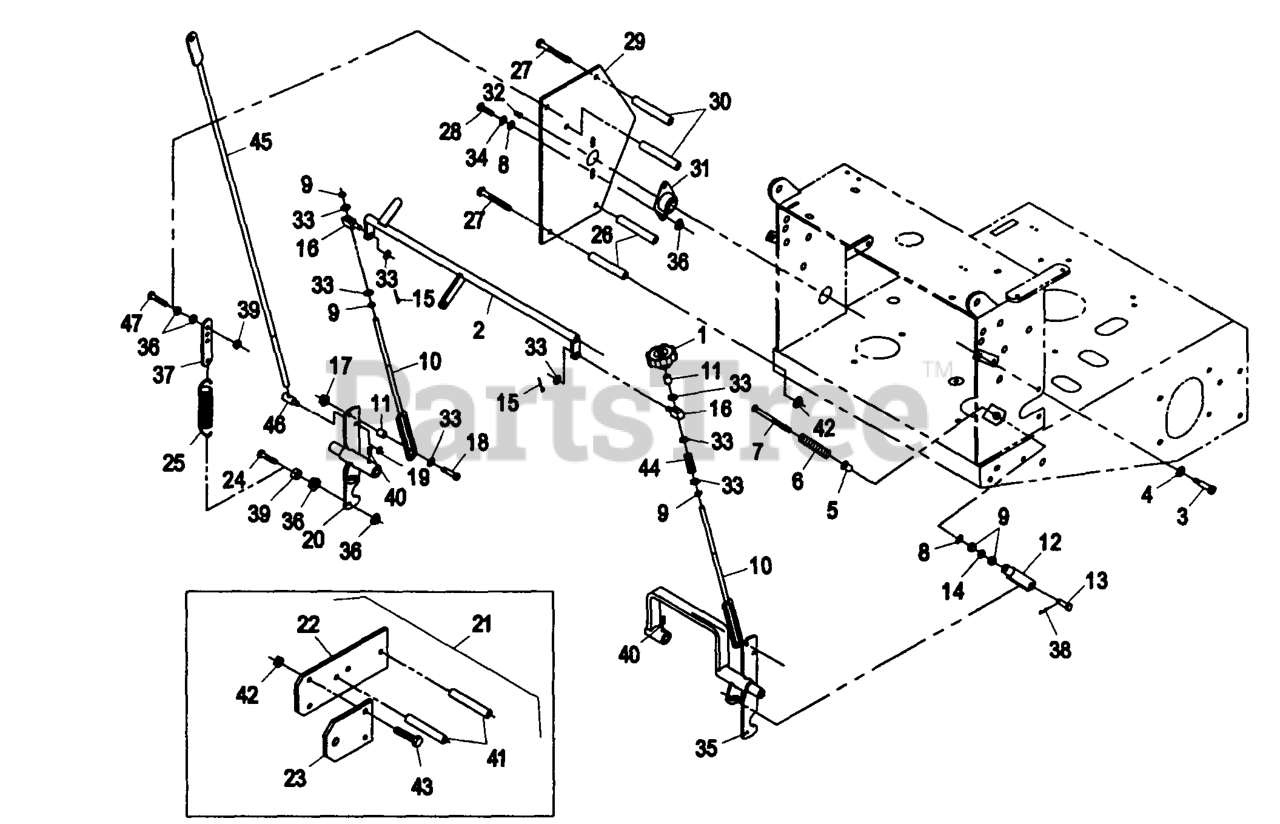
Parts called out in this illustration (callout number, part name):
1	KNOB-TRACKING
2	CRANK-CONTROL, SPEED
3	SCREW-HSH
5	BUSHING-FLANGED
6	SPRING-RETURN, NEUTRAL
7	BOLT-RETURN, NEUTRAL
12	YOKE-ADJUSTABLE
13	PIN-CLEVIS
18	SCREW-HSH
21	Sulky Hitch Kit, (Vik Hydro)
22	MOUNT-HITCH
23	Bracket, Hitch Adapter
25	SPRING-EXTENSION
26	SPACER-SHIELD
30	SPACER-SHIELD
31	BEARING-FLANGE, SIDE
34	WASHER-LOCK
37	TAB-SPRING, EXTENSION
38	PIN-COTTER
40	SCREW-SET
44	SPRING-COMPRESSION
45	ROD-LEVER, DRIVE
47	BOLT-TAP, HH
